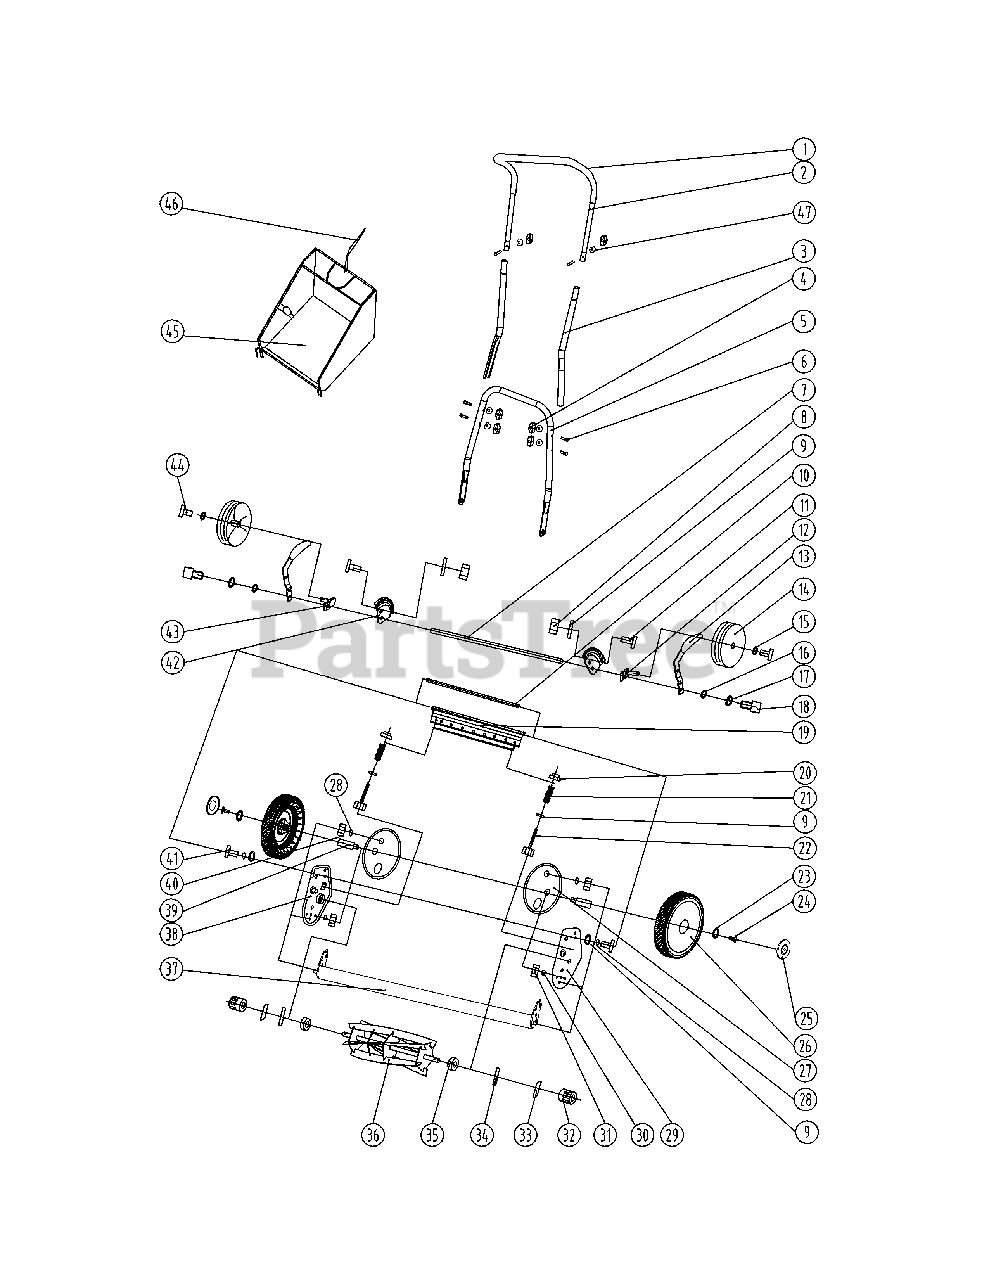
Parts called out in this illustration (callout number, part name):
1	Grip, Handle, 26 x 16 x 630
2	Handle, Upper
3	Handle, Middle
4	Knob, Orange
5	Handle, Lower
6	Bolt, M6 x 35gb/T12
7	Shaft, Rear, Black
8	Nut, M8, Gb/T6172.2
9	Washer, 17 x 8.2 x 1.2
10	Pin,
11	Screw, M8-16gbt70.2
12	Bracket, Rear, LH, Black
13	Handle, Adjustment, Orange
14	Wheel, Rear
15	Washer, 17 x 8.2 x 1.2
16	Washer, Gb/T955
17	Washer, 20 x 13 x 1
18	Bolt, M8 x 24
19	Bracket, Lower Blade, Black
20	Nut, M8 x 1
21	Spacer, 65mm, 17 x 4 x 48
22	Bolt, M8 x 1 x 65
23	Washer, 25 x 6.5 x 1.5
24	Bolt, M6x20, Gb/T5780
25	Hub Cap
26	Wheel, Complete
27	Bracket, Black
28	Washer, Spacer, Gb/T7244
29	Bracket, Support, LH, Black
30	Washer, 20x10.2x1.4
31	Nut, M10, Gb/T6172.2
32	Gear, 41mm, Pa66
33	Support, 19 x 10 x 5
34	Washer, 34 x 15.5 x 1
35	Bearing, 6002z
36	Blade, Roller
37	Shield, Deflector
38	Bracket, Support, RH, Black
39	Axle, Wheel, 19x65.5
40	Nut, M8, Gb/T6170
41	Bolt, M8x16gb/T5781
42	Bracket, Adjustment, 9 Tooth RH
42	Bracket, Adjustment, 9 Tooth LH
43	Bracket, Rear, RH, Black
44	Bolt, M6x10 Gb/T5780
45	Grass Bag
46	Strap, Grass Bag
47	Saddle Washer
